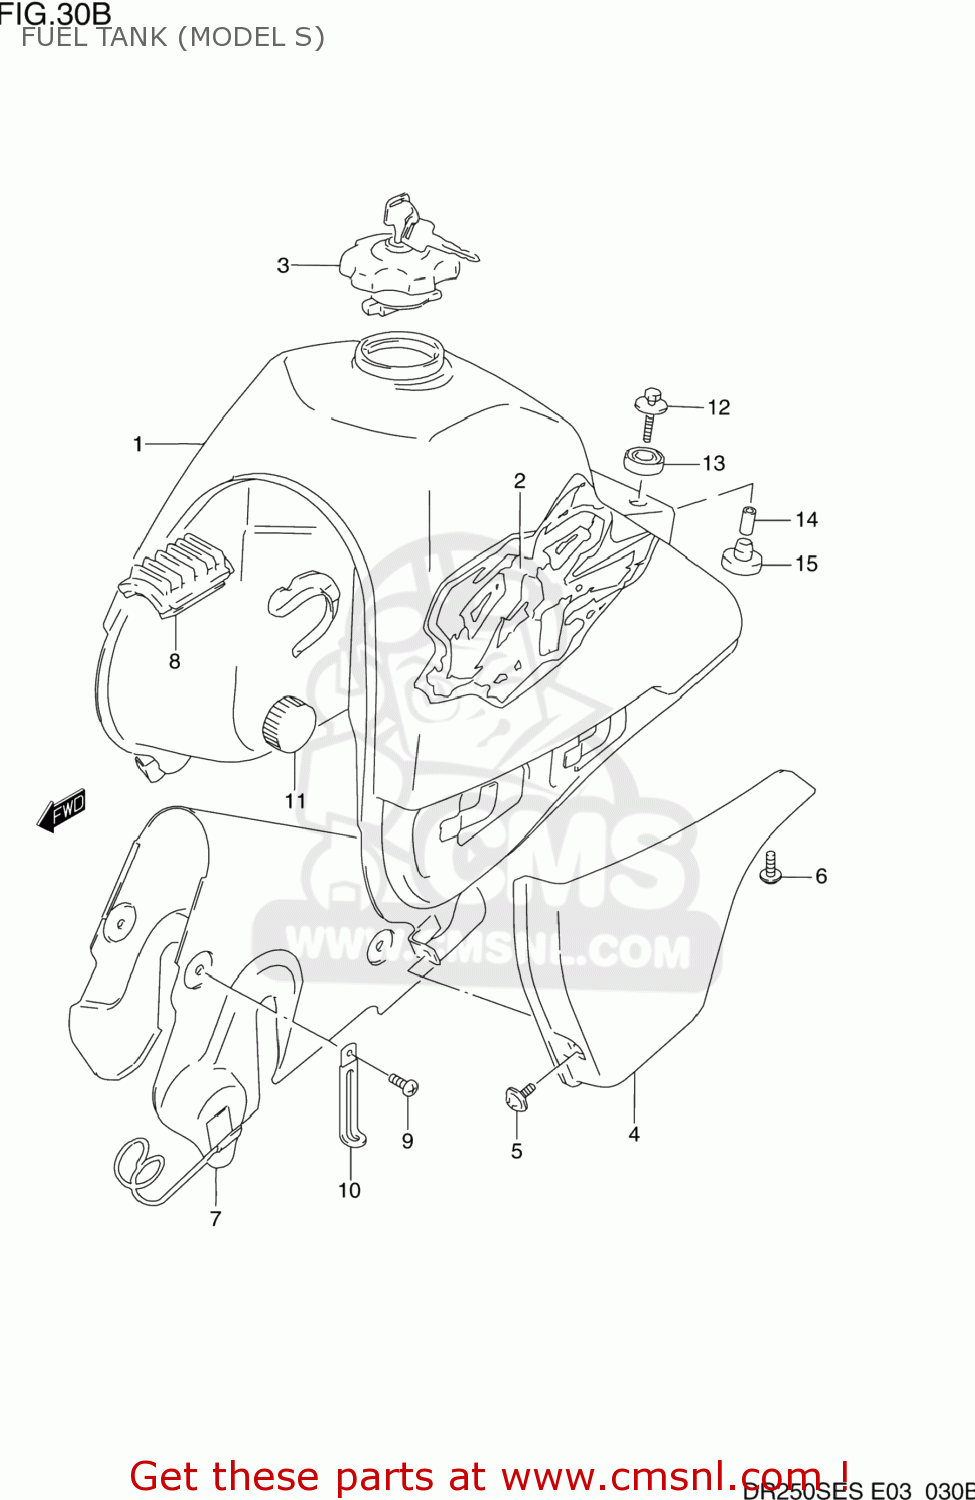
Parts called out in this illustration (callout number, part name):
1	TANK ASSEMBLY,FUEL
2	EMBLEM SET,FUEL TANK
3	CAP SET,FUEL TANK
4	COVER,FUEL TANK,R
5	SCREW
6	SCREW(6X12)
7	SHIELD,FUEL TANK
8	CUSHION,FUEL TANK FR UPR
9	BOLT
10	CLAMP
11	CUSHION
12	BOLT(6X30)
13	CUSHION
14	SPACER
15	CUSHION
